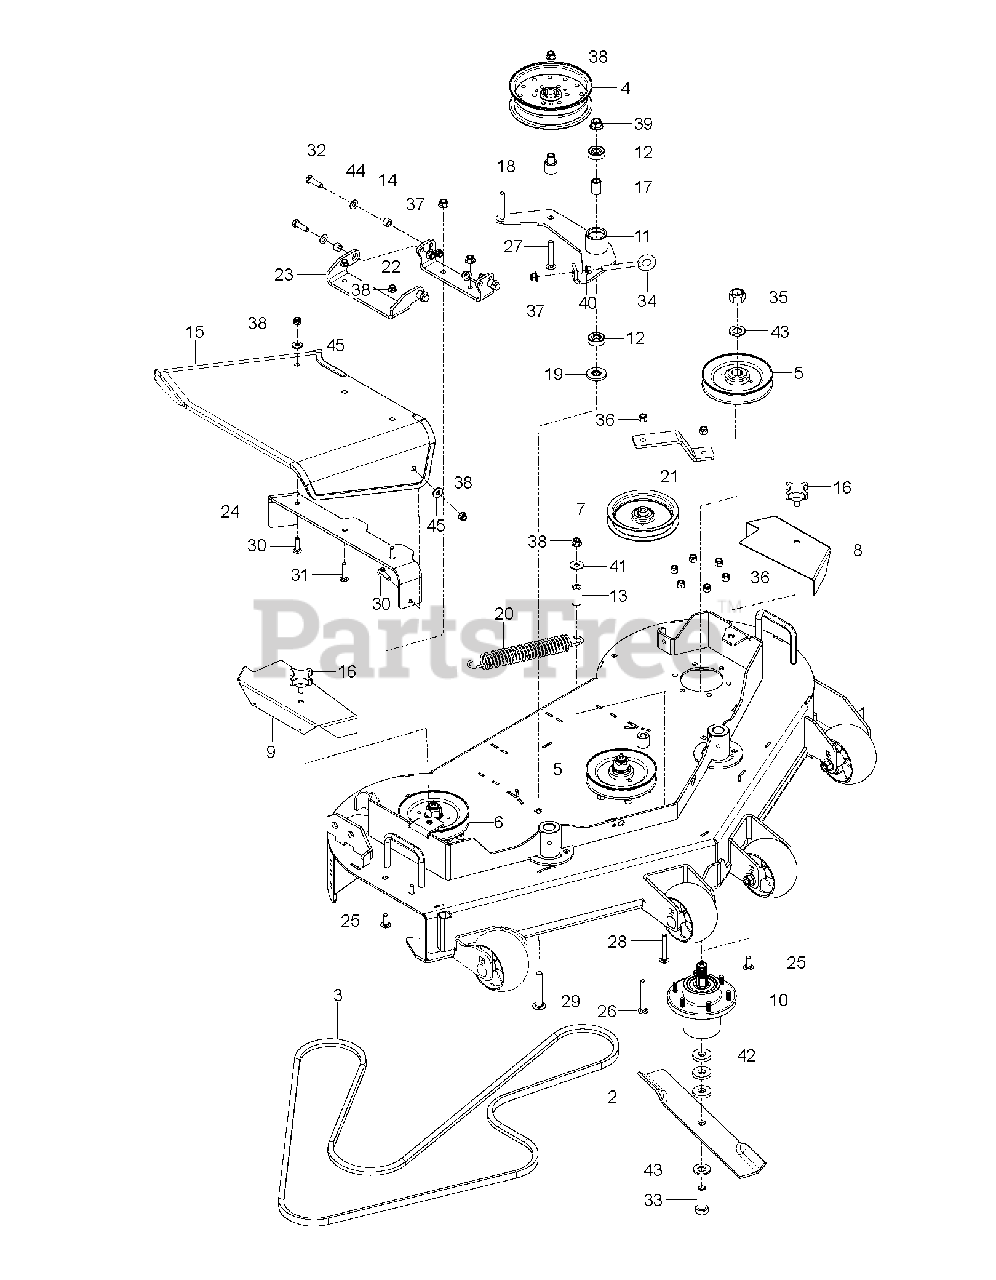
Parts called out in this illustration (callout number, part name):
1	DECK DECK 48" HYDRO W/ DECALS
2	BLADE, 16.500 X .80 LIFT
3	BELT HB 7200519
4	Flat Idler Pulley, 6.00 X .635
5	PULLEY SPINDLE 5.75 X .25 7344
6	PULLEY SPINDLE 5.75 X .76 7344
7	PULLEY FLAT IDLER 5.00X.75 733
8	SHIELD LH SPINDLE FLWLK 509834
9	SHIELD RH SPINDLE 48 FLWLK 509
10	Spindle Housing Assembly
11	ARM IDLER ARM 48 FLWLK WLDMT 4
12	BALL BEARING .500X1.38X.437 BA
13	BUSHING BSHG-SLV .500X.750X1.5
14	BUSHING BUSHING, SLV
15	CHUTE CHUTE, DISCHARGE RUBBER
16	KNOB KNOB, 3/8 -16 X .75
17	SPACER .510 X .75 X 1.1485 935
18	SPACER IDLER 4870200
19	SPACER IDLER ARM 4714600
20	SPRING SPRING EXTENSION .170X1
21	STRAP IDLER 48/52 WALK 3856447
22	BRACKET DISCHARGE PIVOT 510144
23	Discharge Mounting Bracket, LH
24	BRACKET BRACKET DISCHARGE 0478
25	BOLT BOLT RDHDSHSQNK .38-16 X
26	Round Head Bolt
27	Round Head Bolt
28	Round Head Bolt
29	Round Head Bolt
30	BOLT BOLT RDHDSQNK .31-18 X 1.
31	BOLT BOLT RDHDSQNK .31-18 X 1.
32	BOLT BOLT 3/8-16X1-1/4 HEX HEA
33	BOLT BOLT HEX .62-11 X 2.00 G
35	LOCK NUT LOCKNUT, 3/4-16 CROWN
36	NUT NUT, 3/8-16 NYLON LOCK ARI
37	NUT NUT, LK-NYL-FLG .38-16 YWZ
38	NUT NUT, LK-NYL-FLG .31-18 YWZ
39	NUT NUT, LK-NYL-FLG .50-13 YWZ
40	NUT .375-16 WHIZ LOCK FLANGE
41	WASHER WASHER, FL-STL .375 X 1
42	WASHER WASHER, FL-STL .630 X 1
43	WASHER WASHER, .75 X 1.3125 X
44	WASHER WASHER, FL-STL .406 X .
45	WASHER WASHER, FL-STL .38 X .8
